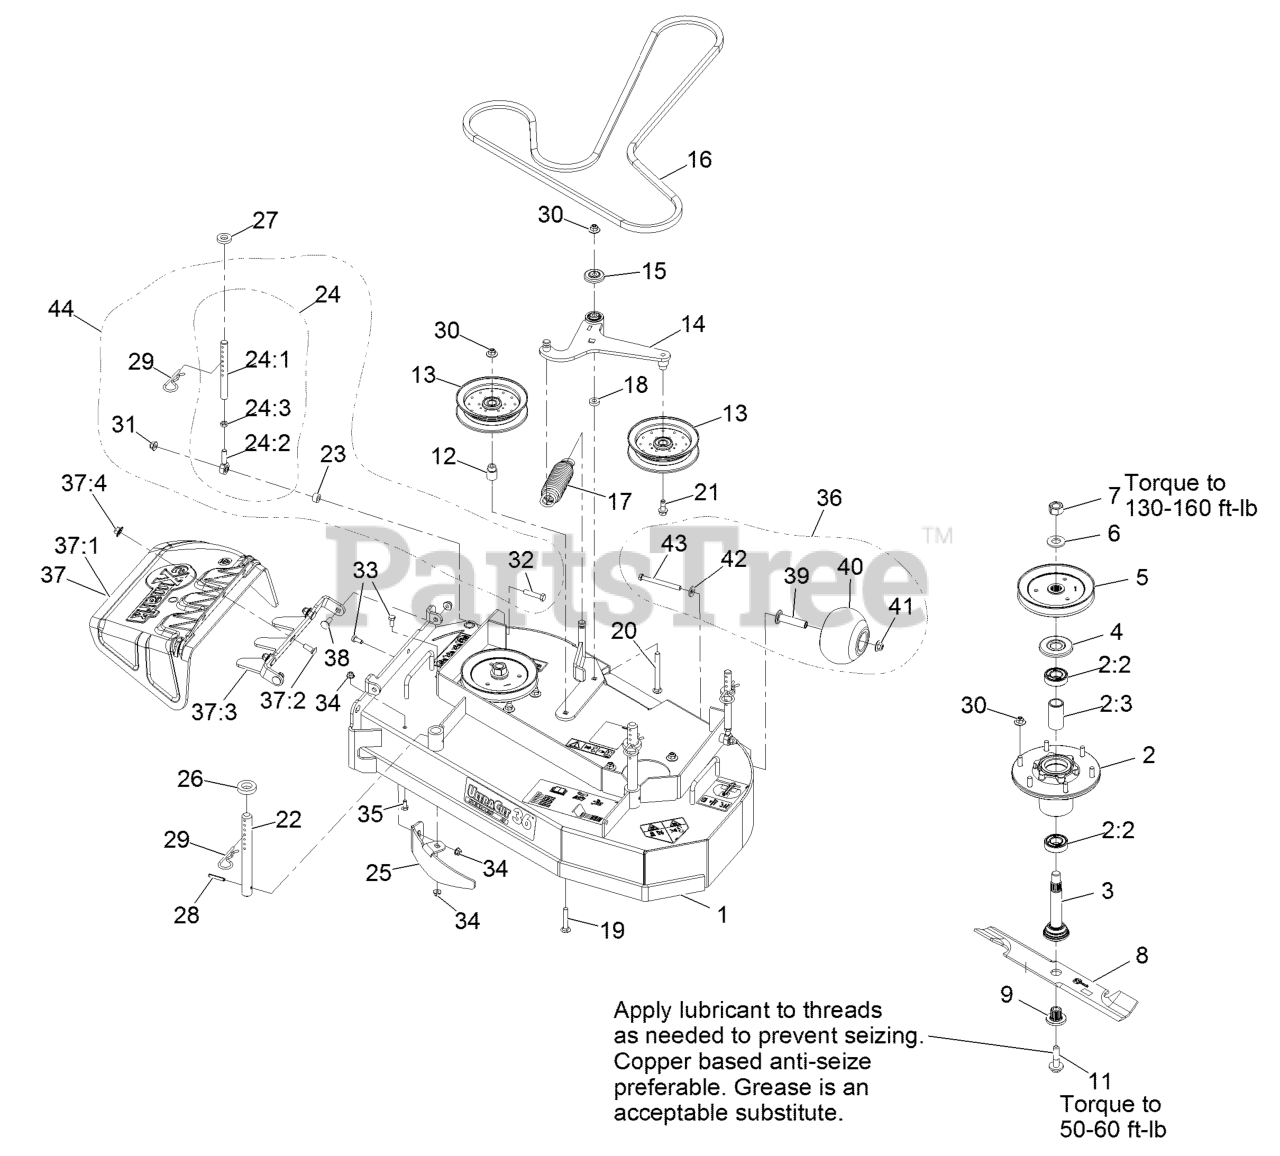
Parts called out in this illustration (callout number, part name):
1	ASM, DECK W/ DECALS, 36"
2	ASM-CUTTER HSG WITH BEARINGS
2:2	BEARING-BALL
2:3	SPACER-BEARING
3	ASM-SPINDLE AND SEAL
4	GUARD,BEARING TOP .989
5	SHEAVE,BLADE DRIVE 6.50
7	NUT-HEX
9	BUSHING,SPLINED
11	SCREW,SEMS 1/2-20 X 2.19
12	BUSHING-IDLER
14	ASM-ARM, IDLER
15	GUARD-TOP
16	BELT-5V
17	SPRING-EXTENSION
18	SPACER
19	Bolt-Carriage 3/8-16 X 2 1/4
20	SCREW-CARR
21	SCREW-HFH
22	ROD,DECK SUPPORT
24:1	LINK,SUPPORT
24:2	BALLJOINT
24:3	NUT-HJ
25	BAFFLE, DOGLEG
26	SPACER-DECK SUPPORT
29	PIN,HAIR COTTER
30	Nut-Nyloc 3/8-16 Flg
31	NUT-HF, NI
32	SCREW-HH
33	SCREW-HH
34	NUT-HF, NI
35	SCREW-HH
36	KIT, ANTI-SCALP ROLLER
37	ASM, DISCHARGE CHUTE
37:1	CHUTE,DISCHARGE
37:2	BRACKET, DISCHARGE CHUTE
37:3	SCREW-CARR
37:4	Nut-Nyloc 3/8-16 Flg
38	SCREW-CARR
39	AXLE, ROLLER
40	ROLLER-SCALP, ANTI
41	Nut-Nyloc 3/8-16 Flg
42	WASHER-BELLEVILLE
43	SCREW-HH 3/8-16 X 3 3/4 GR 8
44	KIT,SUPPORT LINK W/PIN
